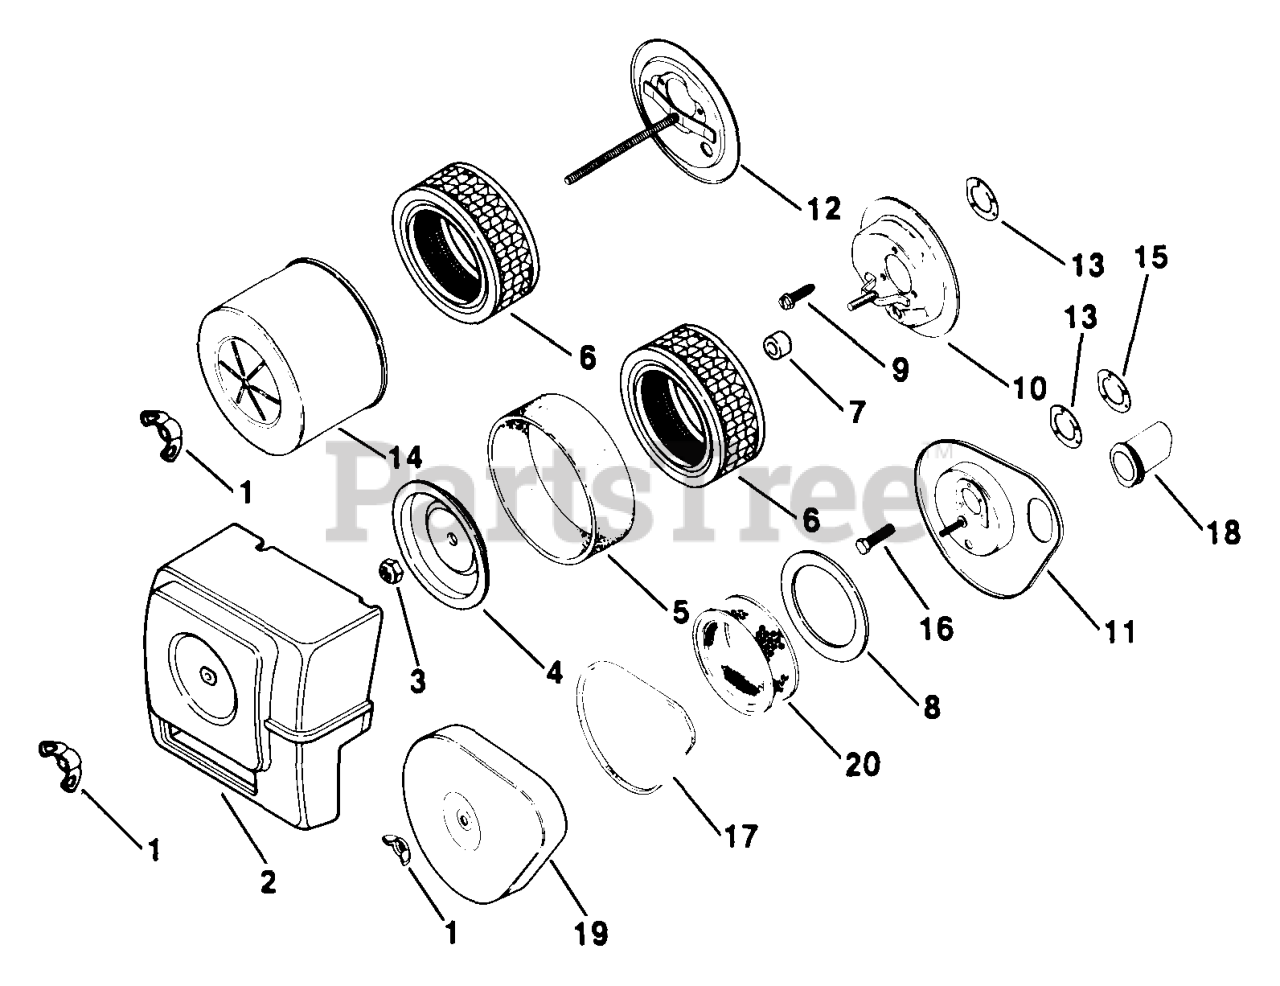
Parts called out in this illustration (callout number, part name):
1	NUT, WING 1/4-20 USE 25 100 15-S
2	COVER - USE 47 096 12
2	COVER, AIR CLEANER
3	NUT, LOCK 1/4-20
4	COVER, INNER AIR CLEANER
5	ELEMENT, PRE-CLEANER
7	SEAL, BREATHER
9	SCREW, HD TAP #10-32x9/16" USE 25 086 102-S
10	BASE, AIR CLEANER
13	GASKET, AIR CLEANER
